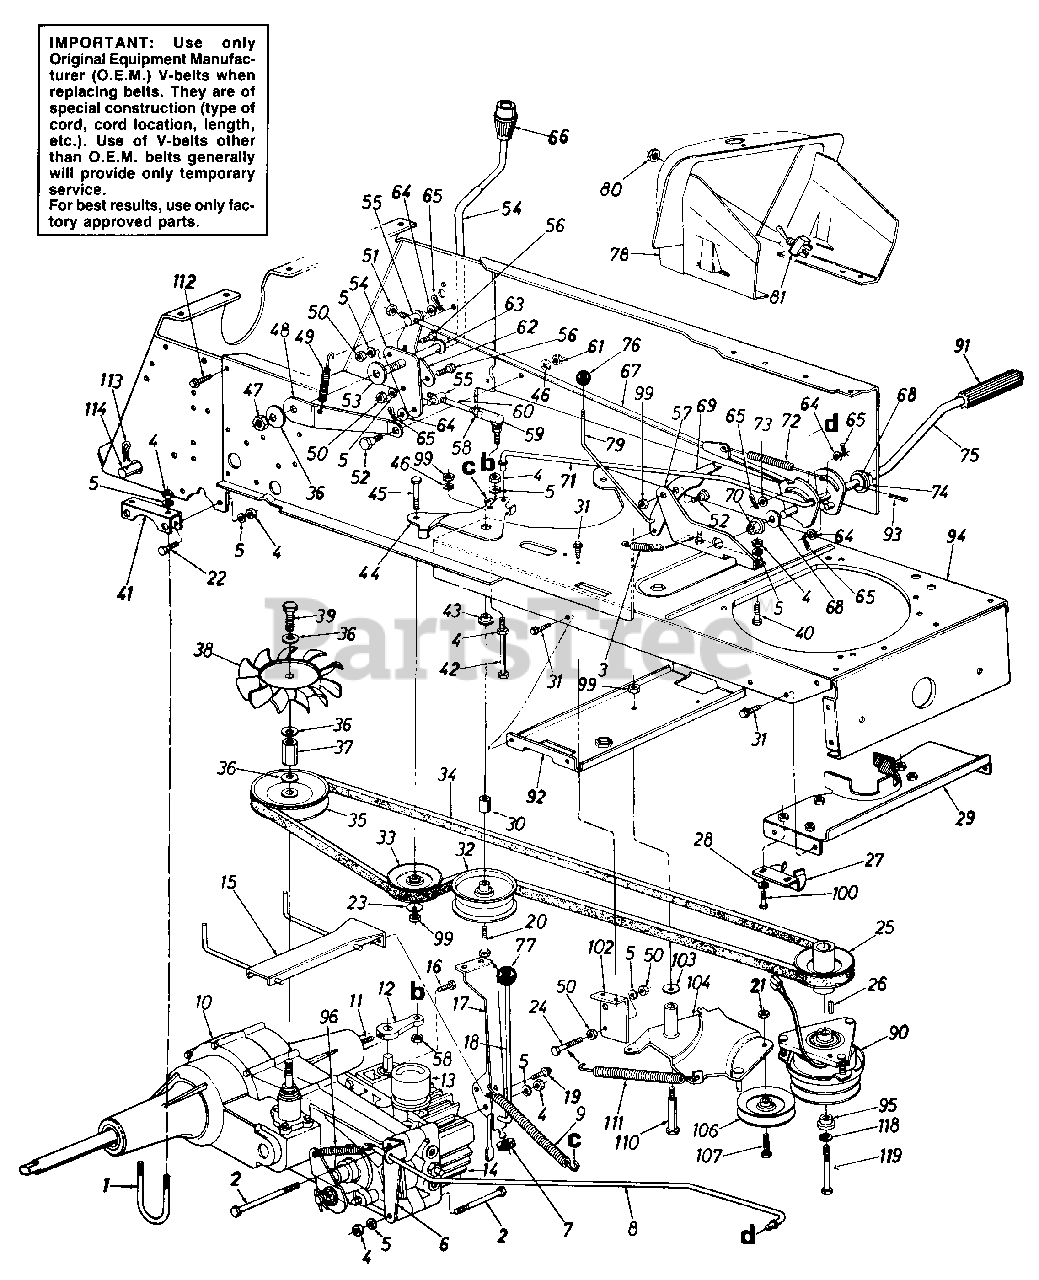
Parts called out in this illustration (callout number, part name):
1	U-Bolt 5/16-18 x 3.25" Lg.
2	Hex Patch Bolt 5/16-18 x 4.5" Lg. (Gr. 5)
3	Ext. Spring .5" O.D. x 1.55"
4	Hex Nut 5/16-18 Thd.
5	L-Wash. 5/16" I.D.
6	Brake Rod Guide Brkt.
7	Rubber Wash. .33" I.D. x .87"
8	Brake Rod
9	Ext. Spring .62" O.D. x 6.12" Lg.
10	Transaxle
11	Set Screw 5/16-24 x .38" Lg.
12	Pintle Shift Lever
13	Reservoir
14	Hydrostatic Pump
15	Belt Guard Ass'y.
16	Hex Bolt 5/16-18 x 4.5" Lg. (Gr. 5)
17	Transaxle Torque Bracket
18	Transaxle Control Rod
19	Hex Wash. Hd. B-Tap Scr. 5/16-1 8
20	Hex Bolt 3/8-16 x 2.75" Lg.
21	Hex Cent. Lock Nut 3/8-16 Thd.
22	Hex Bolt 5/16-18 x .75" Lg. (Gr. 5)
23	Fl-Wash. .385" I.D. x .87" O.D.
24	Hex Bolt 5/16-24 x 1.75" Lg.
25	Engine Pulley
26	Sq. Key 1/4 X 1.5" Lg.
29	Belt Keeper Brkt. Ass'y.
30	Spacer .375" I.D. x .75" Lg.
31	Hex Wash. Hd. TT-Tap Scr. 1/4 -20 x .5" Lg.
32	Fl-Idler Pulley 3.25" Dia.
33	V-Belt Idler
34	V-Belt
35	Transmission Pulley 4.25" O.D.
36	Bell-Wash. .56" I.D. x 1.5
37	Fan Adapter Nut 9/16-18 Thd.
39	Hex Bolt 9/16-18 x .5" Lg.
40	Hex Bolt 5/16-18 x .75" Lg.
41	Transaxle Mtg. Bracket
42	Hex Bolt 5/16-18 x 2.75" Lg.
43	Shld. Spacer .625" I.D.
44	Clutch Idler Bracket
45	Hex Bolt 3/8-16 x 1.5" Lg.
46	L-Wash. 3/8" I.D.
47	Hex Jam Nut 1/2-20 Thd.
48	Speed Control Rod Torque Brkt.
49	Ext. Spring 2.5" Lg.
50	Hex Nut 5/16-24 Thd.
51	Hex Jam Nut 3/8-24 Thd.
52	Shld. Bolt .50" Dia. x .170"
53	Fiber Washer .54" I.D. x 1.75"
54	Speed Control Handle Ass'y.
55	Ferrule 3/8-24 Thd.
56	Hex Bolt 5/16-24 x .62" Lg.
57	Foot Pedal Mtg. Brkt.
58	Hex Jam Nut 3/8-24 L.H. Thd.
59	Ball Joint Ass'y.
60	Control Rod 3/8-24 x 3.75" Lg.
61	Hex Nut 3/8-16 Thd.
62	Speed Selector Handle Brkt.
63	Fl-Wash. .531" I.D. x 1.25" O.D.
64	Fl-Wash. .385" I.D. x .62" O.D.
65	Internal Cotter Pin
66	Shift Knob
67	Neutral Return Rod
68	Fl-Wash. .64" I.D. x 1.24" O.D.
69	Parking Brake Lock Brkt.
70	Hex Flange Brg. .634" Dia.
71	Clutch Idler Rod
72	Extension Spring 8" Lg.
73	Fl-Wash. .344" I.D. x .62" O.D.
74	Flange Bearing w/Flats
75	Foot Pedal Ass'y.
76	Ball Knob Brake
77	Ball Knob 1/4-20 Thd.
78	Dash Panel Ass'y.
79	Parking Brake Link
80	Hex Nut 1/2-27 Thd.
81	Toggle Switch
90	Electric Clutch
91	Foot Pad
92	Deck Idler Support Brkt.
93	Cotter Pin 1/8" Dia.
94	Lower Frame
95	Shoulder Spacer
96	Ext. Spring 3.675" Lg.
99	Hex Cent. L-Nut 3/8-16 Thd.
100	Hex Bolt 5/16-18 x .75" Lg. (Gr. 5)
102	Parking Brake Mtg. Brkt.
103	Bell-Wash. .380" I.D. x .88" O.D.
104	Idler Brkt. Deck Ass'y.
106	V-Belt Idler
107	Hex Bolt 3/8-24 x 1.5" Lg.
110	Shld. Bolt .498" Dia. x 2.05"
111	Ext. Spring 4.0" Lg.
112	Hex Wash. AB-Tap Scr. 5/16 x .75" Lg.
113	Hitch Pin Clip
114	Hitch Rod
118	L-Wash. 7/16" I.D.
119	Hex Bolt 7/16-20 x 3.75" Lg.
